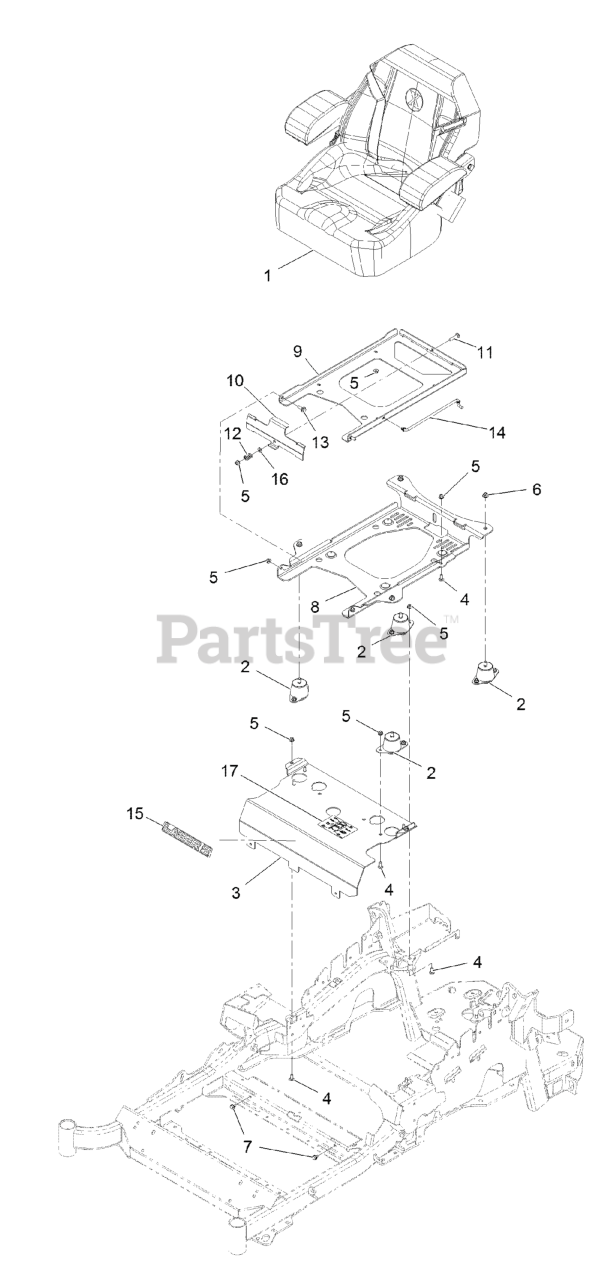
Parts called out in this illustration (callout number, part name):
1	SEAT-EXMARK STANDARD
2	ISOLATOR-SEAT
3	Panel,Seat Mount-Front
4	SCREW-CARR
5	NUT-HF, NI
6	NUT-HF, NI
8	PLATE-TILT, SEAT SUPPORT
9	PLATE-FRAME, SEAT
10	PLATE-LATCH, SEAT
11	BOLT-CARR
12	SPRING-COMPRESSION
13	SCREW-SHOULDER
14	ROD-PROP
15	DECAL, LAZER MODEL
16	WASHER-PLAIN
17	DECAL-SERVICE AID
